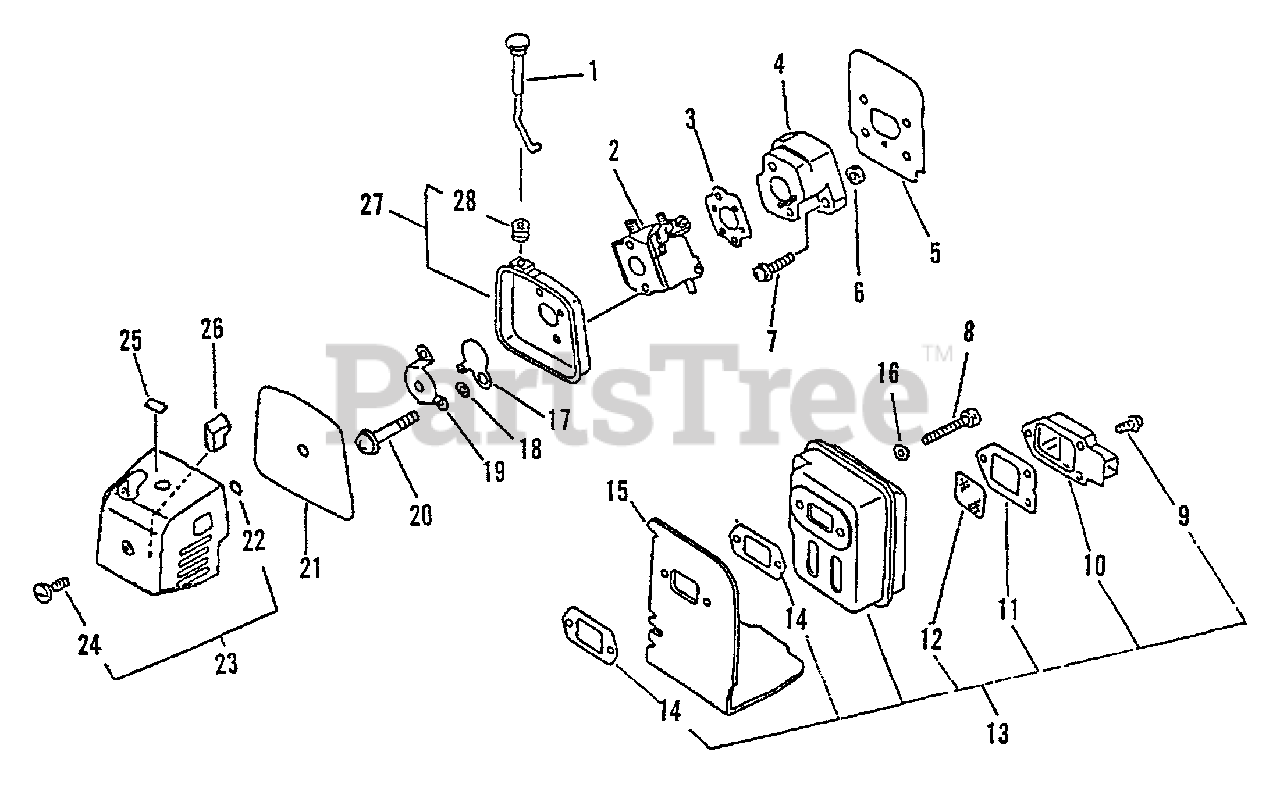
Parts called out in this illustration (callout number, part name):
1	ROD, CHOKE
2	CARBURETOR C1U-K23
3	GASKET, INTAKE
4	INSULATOR, INTAKE
5	SHIELD, INTAKE
7	SCREW - 5X20
8	SCREW - 5X55
9	SCREW - 4X10
10	GUIDE, EXHAUST - OUTER
11	GASKET, EXHAUST
12	SCREEN, SPARK ARRESTOR
13	MUFFLER ASSY
14	GASKET, EXHAUST
15	COVER, EXHAUST
16	WASHER - 5
17	SHUTTER, CHOKE
18	WASHER - 5
19	BRACKET, AIR CLEANER
20	SCREW - 5X55
21	FILTER, AIR
22	O-RING - 4
23	AIR FILTER COVER ASSY
25	LABEL - CHOKE
28	CASE, AIR FILTER
